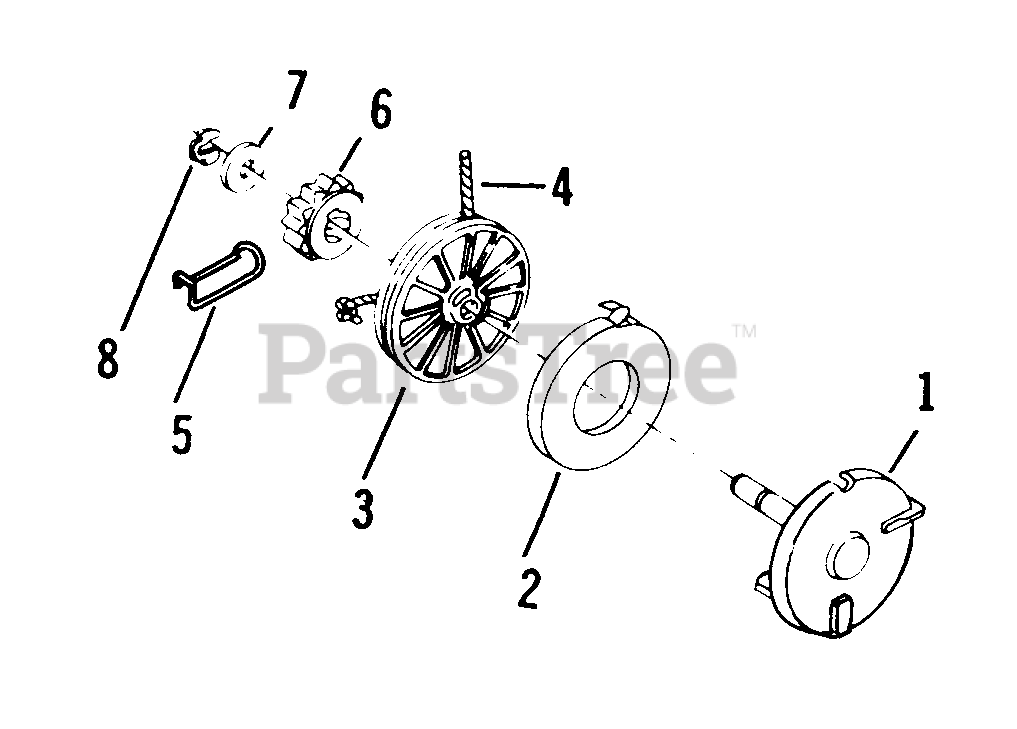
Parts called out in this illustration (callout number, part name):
1	Spring Cup and Pin Assembly
2	Spring and Retainer Assembly
3	Pulley
4	Rope
5	Spring-Drag
6	Pinion
7	Washer
8	Retainer
